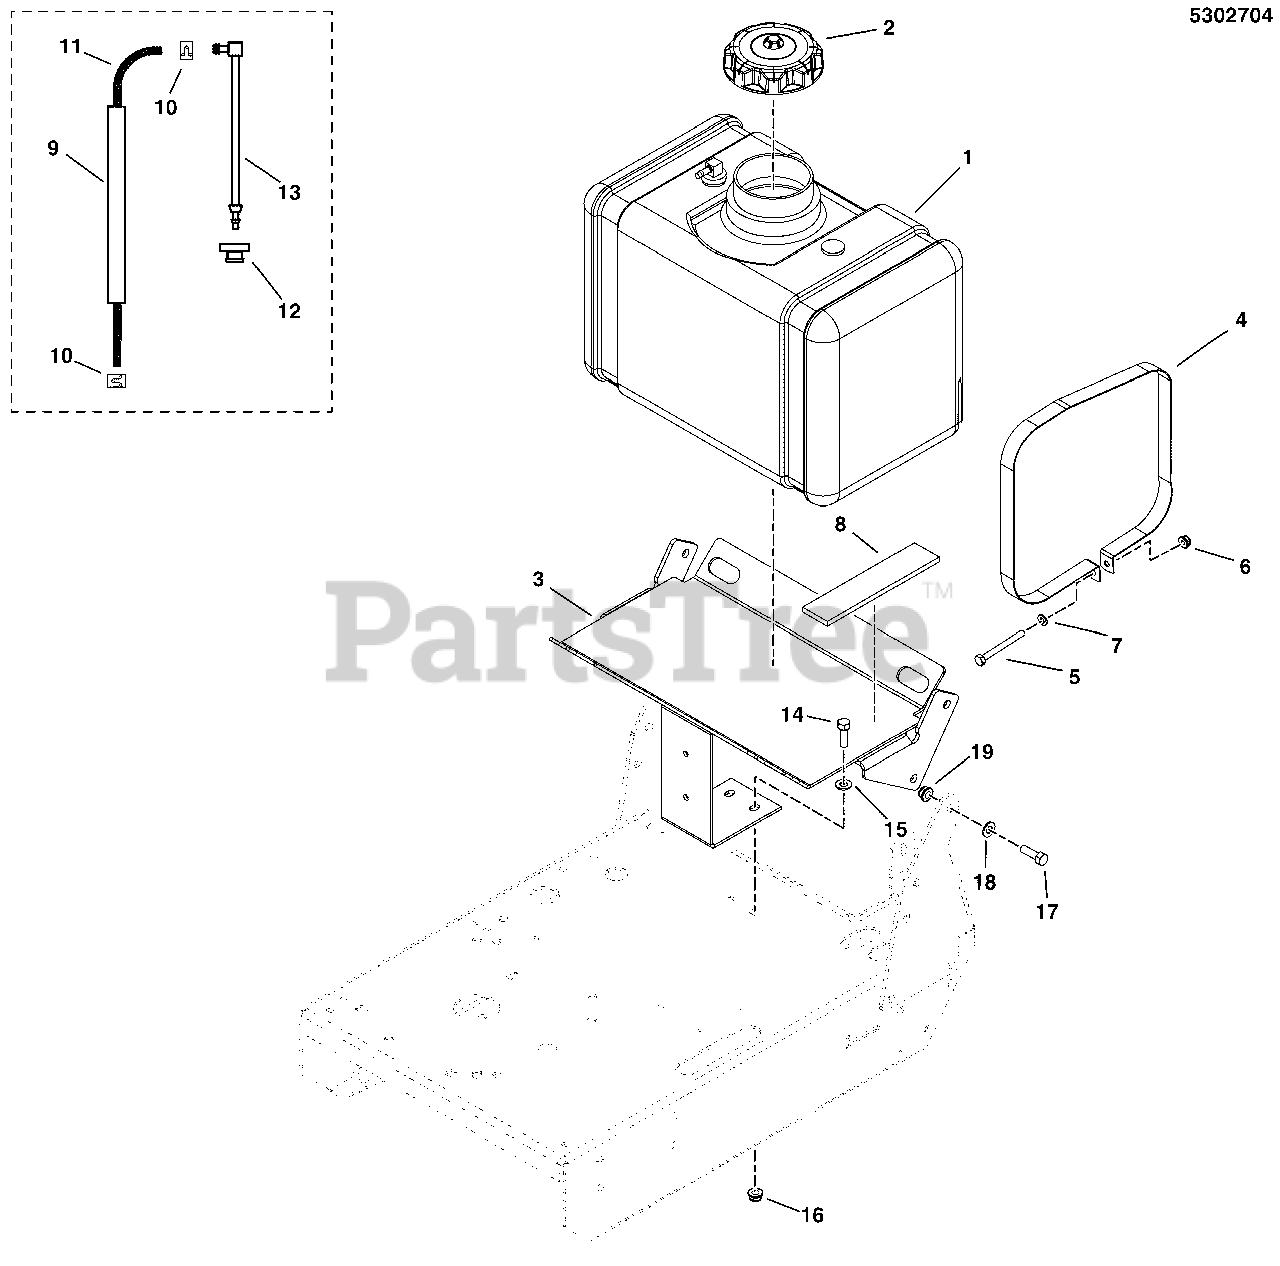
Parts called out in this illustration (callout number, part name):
1	TANK, 5 GAL, W DROP TUBE/VENT
2	FUEL CAP, 3-1/2", MANAGED VENT OUT, 12"
3	WELD, TANK MOUNT, HYDROCUT - ORG
4	STRAP, FUEL TANK - SNP PRO DDS - BLK
5	BOLT, HEX, 1/4-20 X 2-1/2, TFL, GD5, CZ
6	NUT, 1/4-20 HEX NYLOCK FLANGE (5025391)
7	WASHER, 1/4 SAE (5025154)
8	PAD, RUBBER MOUNT
9	WIRE LOOM, 1/2 ID X 14 IN
10	CLAMP, HOSE, EXTERNAL, 1/2 - RED
11	HOSE, 1/4" FUEL, 20.00"
12	BUSHING-FUEL TANK RED RUBBER (SV)
13	PICKUP TUBE ASM, FUEL TANK, 8.0"
14	BOLT, 5/16-18 X 1 GD5
15	WASHER, 5/16 SAE
16	NUT, 5/16-18 HEX NYLOCK FLANGE
17	BOLT, 3/8-16 X 1-1/4 GD5
18	WASHER, 3/8 SAE
19	NUT, 3/8-16 HEX NYLOCK FLANGE
